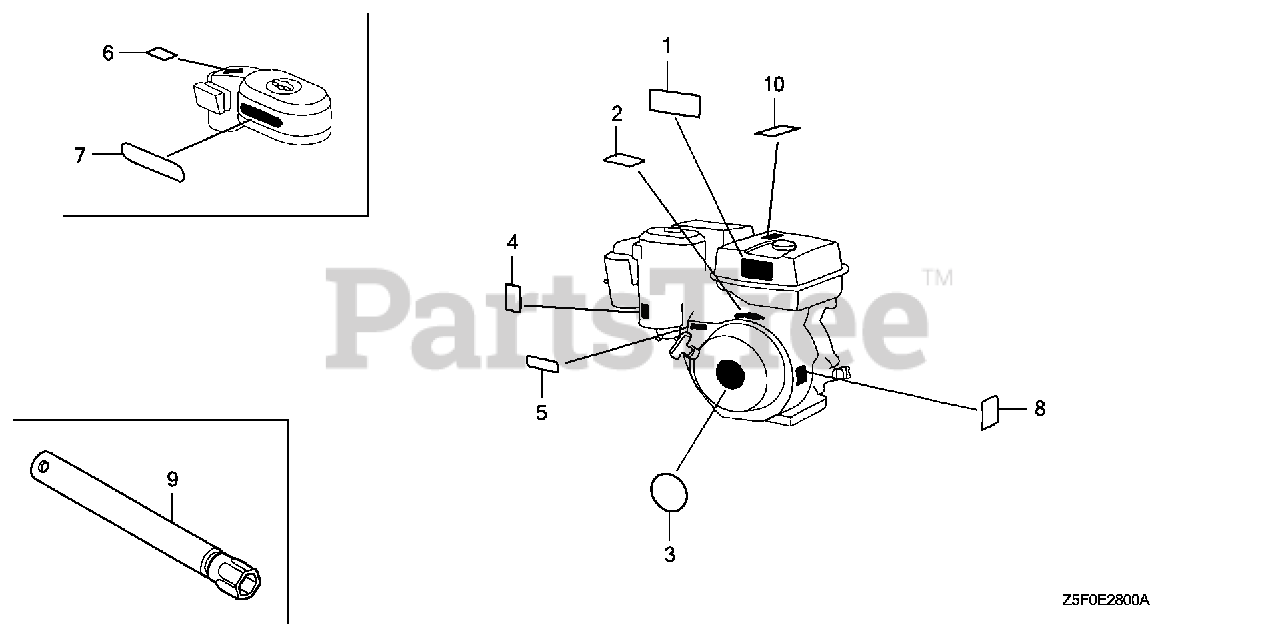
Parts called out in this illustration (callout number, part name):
1	MARK, OPERATOR CAUTION (ENGLISH)(MADE IN JAPAN)
3	EMBLEM (GX240)
4	MARK, CHOKE
5	MARK, THROTTLE INDICATION
10	MARK, EX. CAUTION (ENGLISH)
